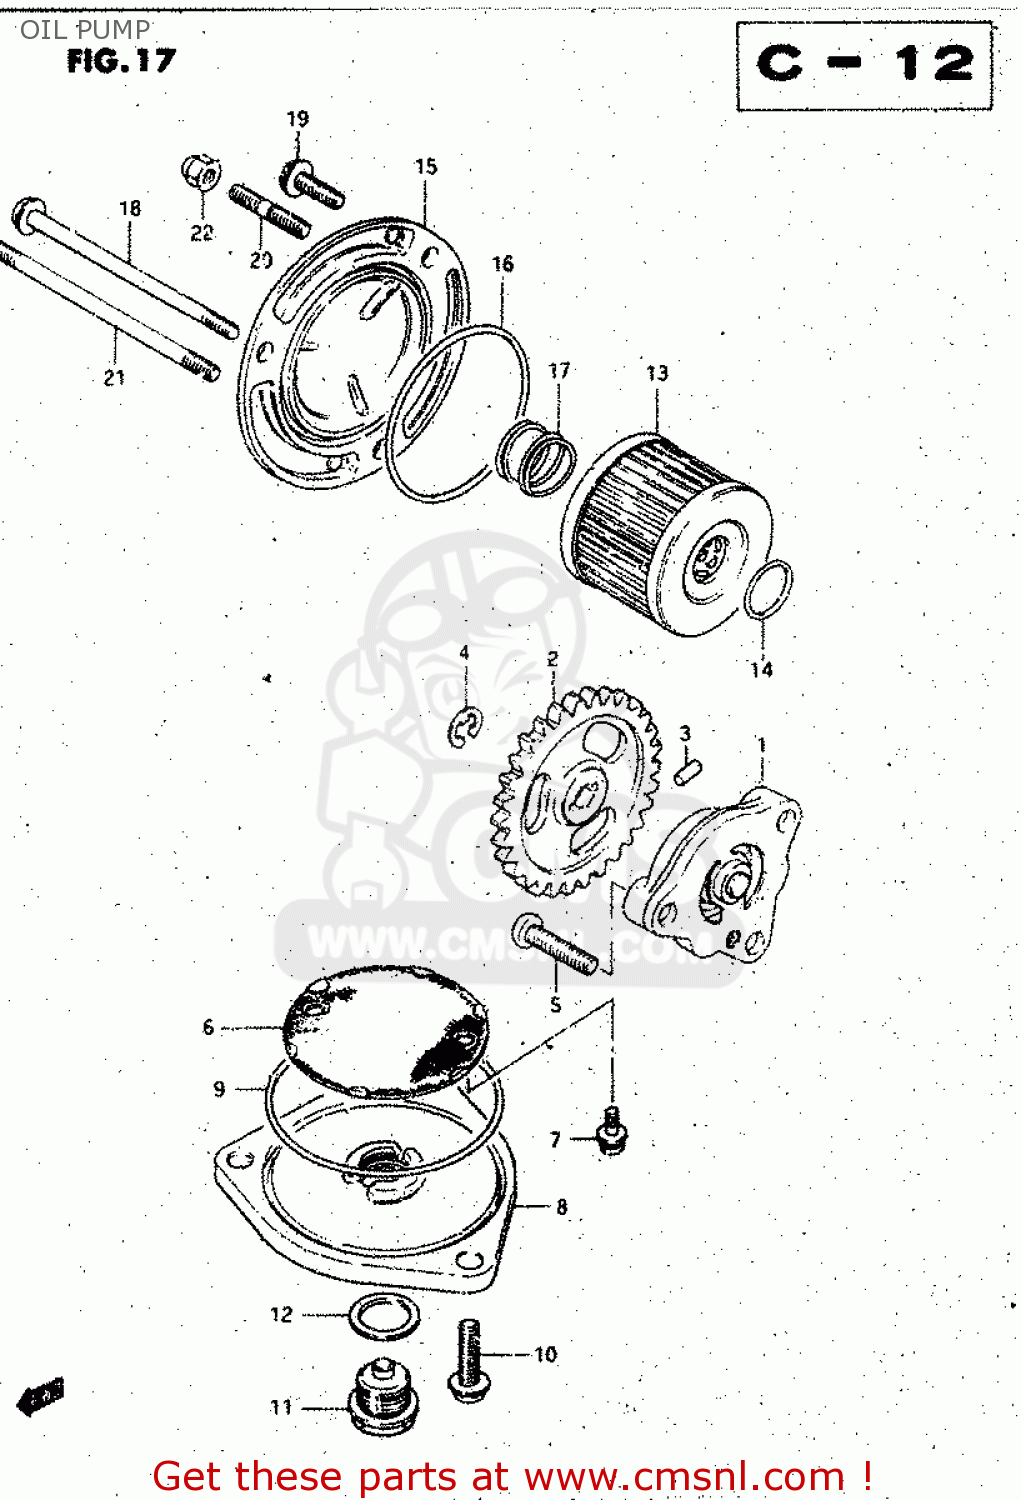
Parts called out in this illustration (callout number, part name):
1	PUMP ASSY,ENGINE OIL
2	GEAR,ENG OIL PUMP DRIVEN(NT:30
3	PIN(2.5X11.8)
4	E.RING
5	SCREW
6	STRAINER,ENGINE OIL
7	SCREW
8	CAP,OIL STRAINER
9	O RING(D:2.4,ID:60.5)
10	SCREW
11	PLUG
12	GASKET(13.8X18.8X4.8) (NAS)
13	FILTER ASSY,ENGINE OIL
14	O RING(D:1.9,ID:13)
15	CAP,OIL FILTER
16	O RING(D:2.4,ID:52.6)
17	SPRING
18	BOLT
19	SCREW
20	STUD 6X12
21	STUD BOLT, 6X8
22	NUT
